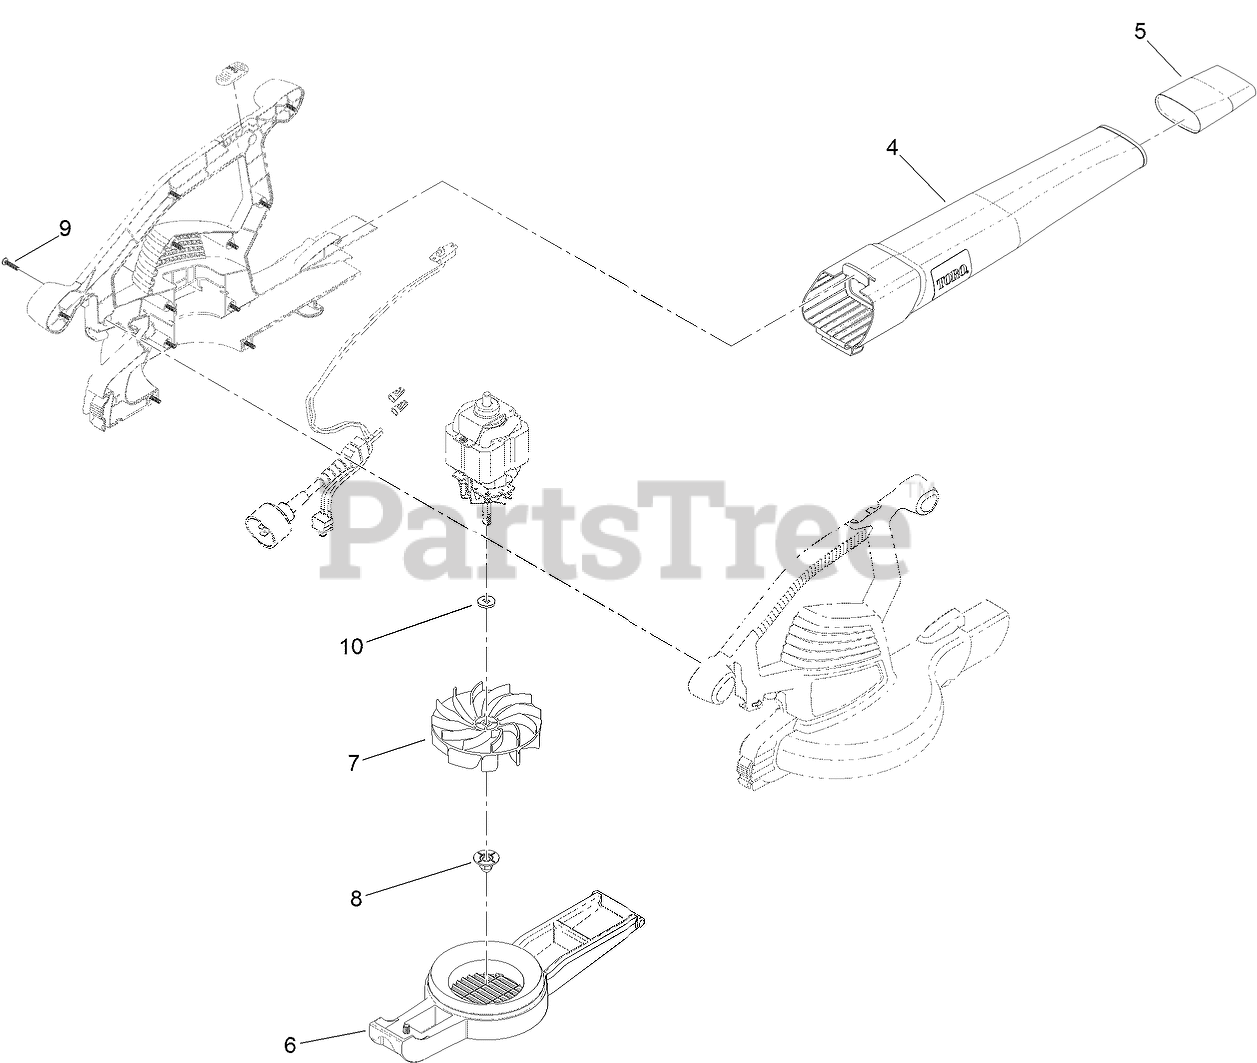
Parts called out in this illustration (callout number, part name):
4	TUBE-BLOWER
5	TUBE-INSERT, SUPER
6	COVER-INLET
7	IMPELLER-PLASTIC, 9 BLADE
8	NUT-IMPELLER
9	SCREW-PPH
10	WASHER-IMPELLER
